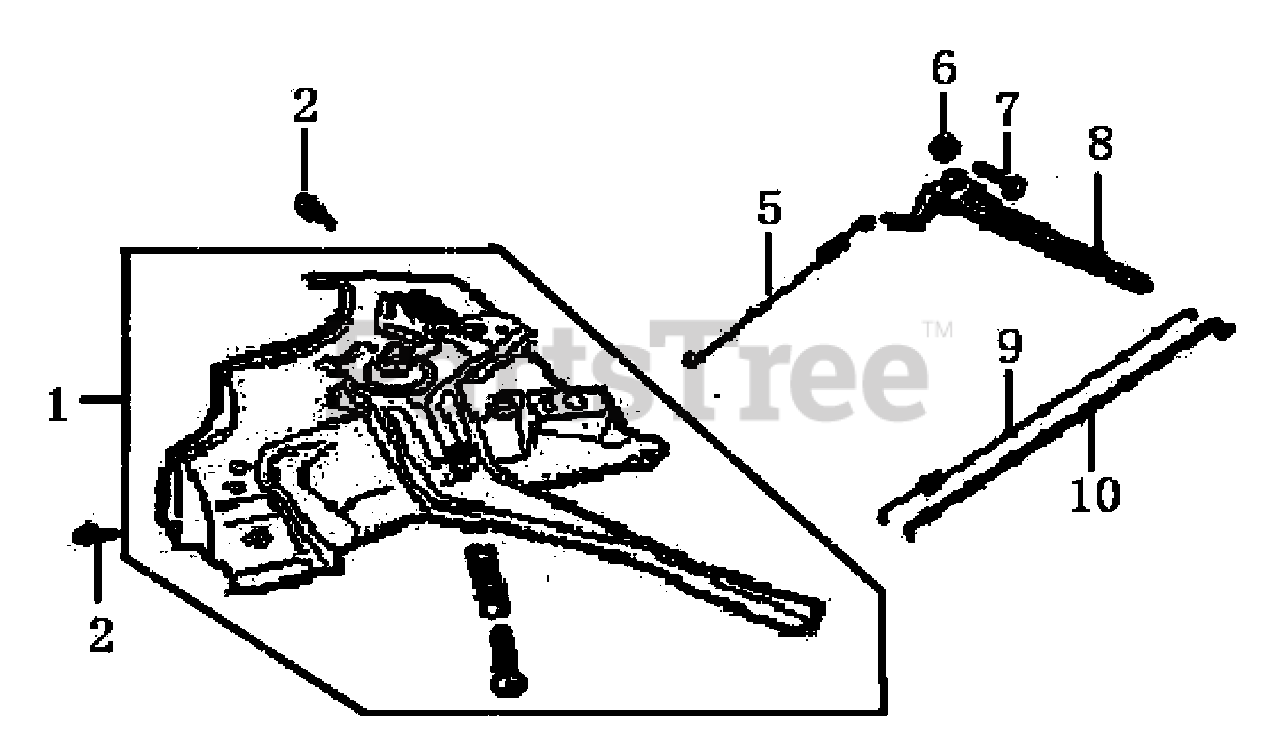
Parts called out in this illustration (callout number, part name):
1	CONTROL ASSY.
2	BOLT, FLANGE
5	SPRING, CABLE RETURN
6	NUT, FLANGE
7	BOLT, QUADRATE HEAD
8	ARM, GOVERNOR
9	SPRING, THROTTLE RETURN
10	ROD, GOVERNOR
